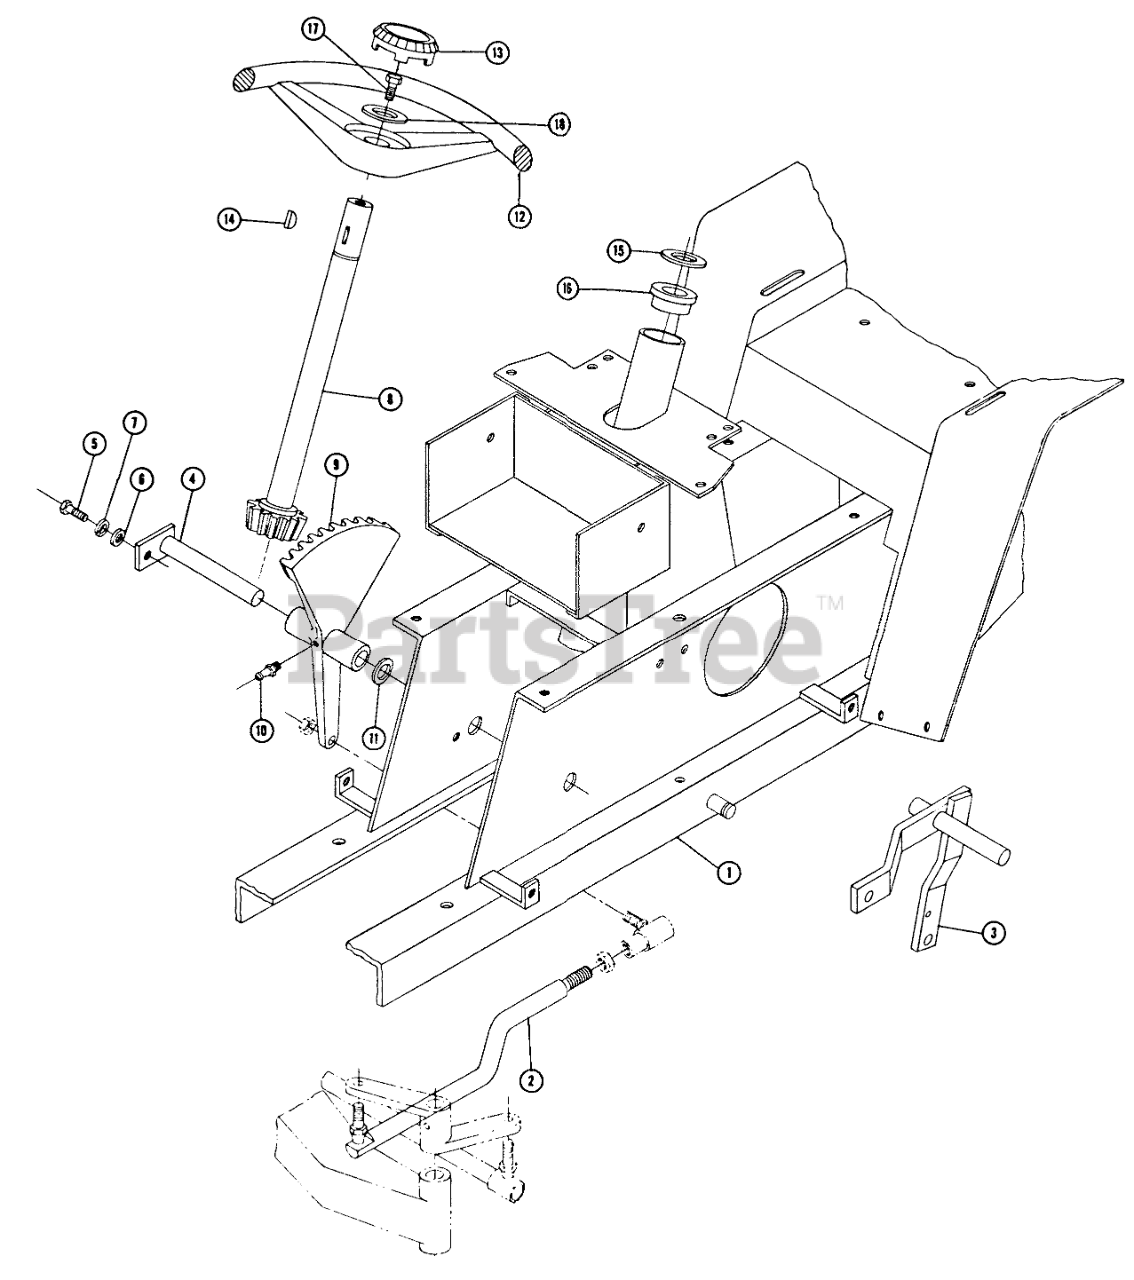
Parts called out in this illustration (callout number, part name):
1	Ass-y. Frame
3	Ass-y. Lift Lever
4	Pivot Pin
5	Bolt, 1/4-x 1/2
6	Washer
7	Lockwasher
8	Ass-y. Shaft and Pinion
11	Washer-Shim
12	BULLT 399C
13	Insert
14	Key
15	Washer
17	Bolt-Nylok 3/8-16 x 5/8
18	WASHER
